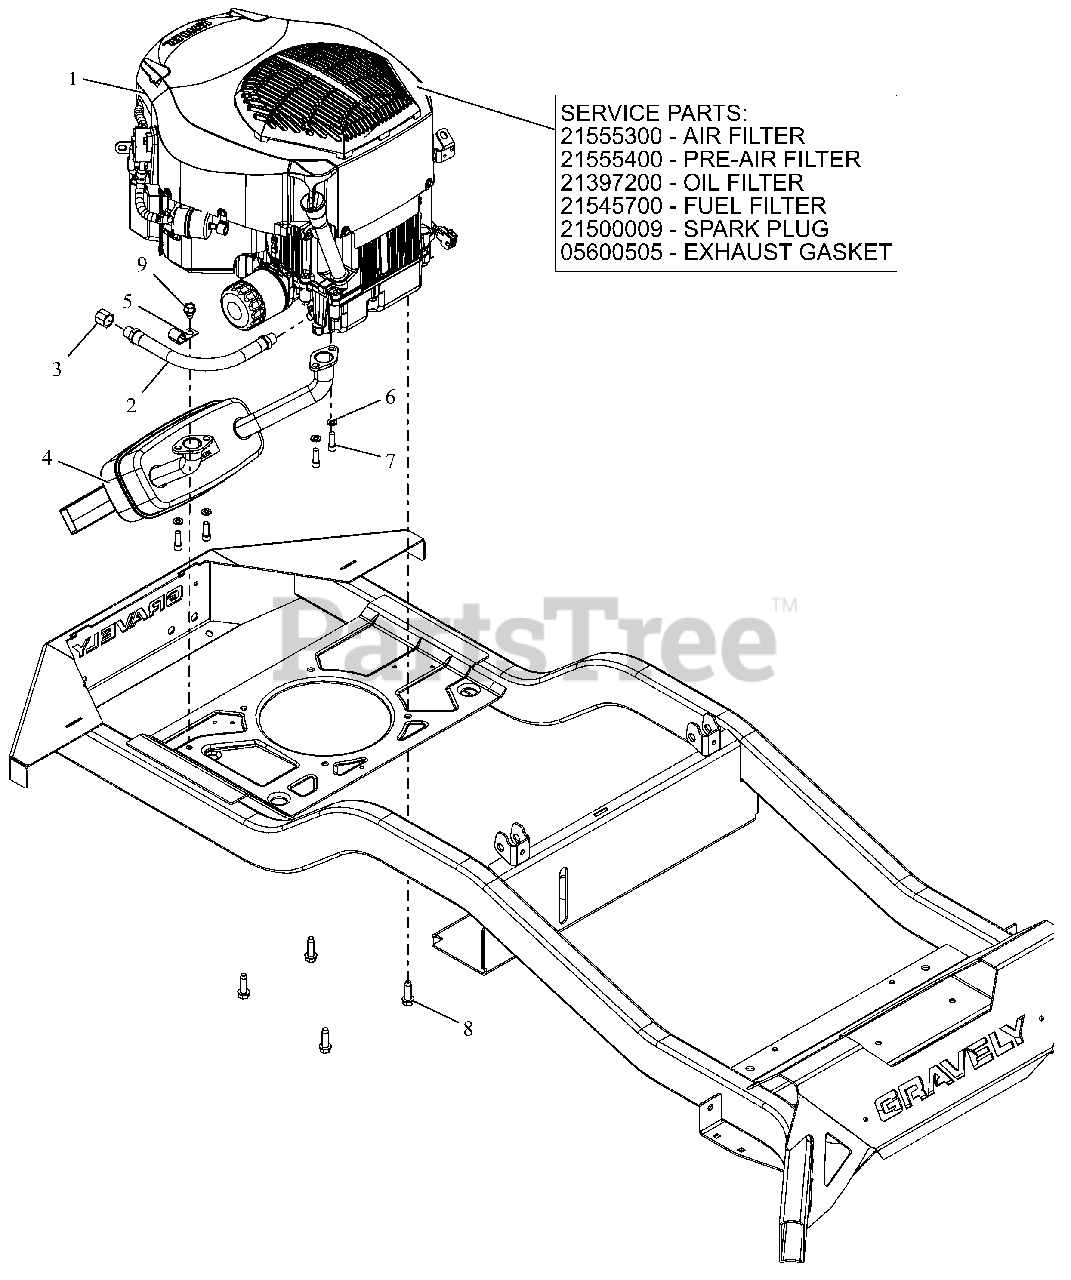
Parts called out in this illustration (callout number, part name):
1	ENGINE, KOHLER - KT740
1	AIR FILTER, KOHLER
1	PRE CLEANER, KOHLER
1	FILTER, OIL - KOH CV20
1	FILTER-FUEL KOHLER COURAGE PRO
1	PLUG, SPARK KOHLER
1	GASKET, MUFFLER KOHLER TWIN
2	HOSE,HYD .38-11-0K M6NO-M6N0
3	PIPE CAP 3/8 NPT FEMALE
4	MUFFLER, KOHLER
6	@WSHR-LK .31X.078 REG YWZC
7	SCR, SKH .312-18X.875 GR8 ZCC
8	@SCR-TAP .38-16X1.25 HWH TR YZ
9	@SCR-TAP .38-16X.50 HWH TR YWZ
